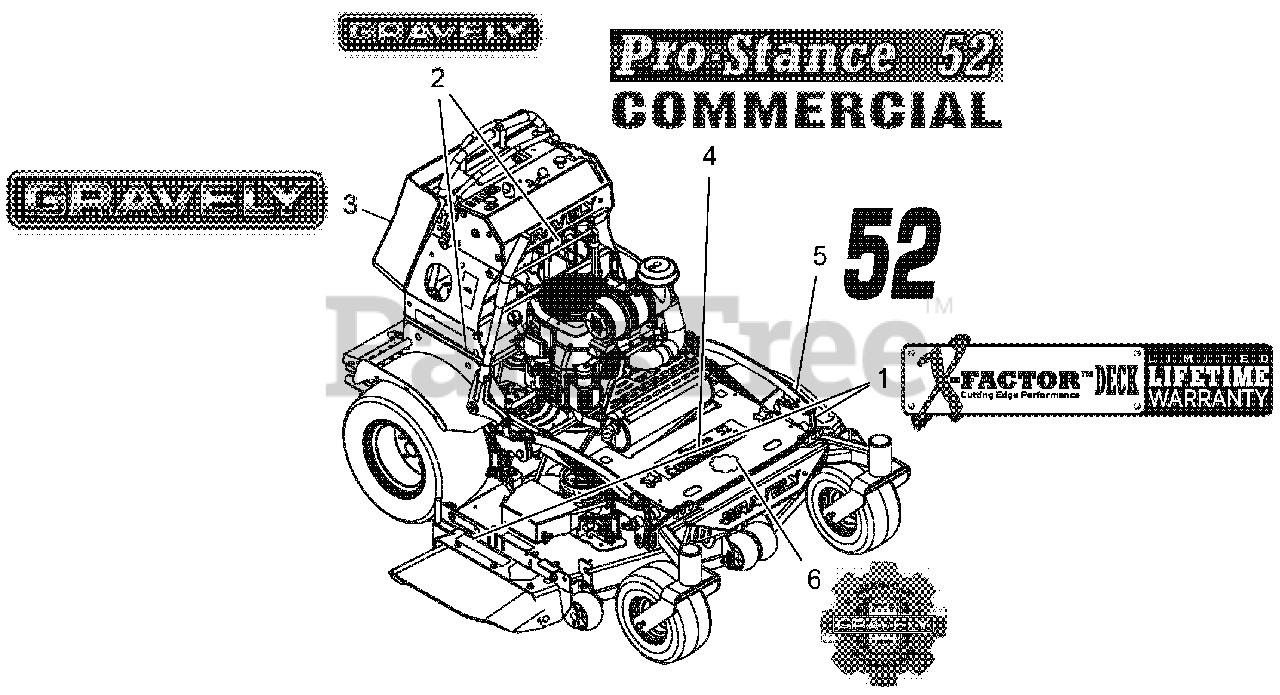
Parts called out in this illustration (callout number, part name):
1	DECAL, X-FACTOR DECK
2	DECAL, 9.5" GRAVELY LOGO
3	DECAL, FUEL TANK-GRAVELY
4	DECAL, PROSTANCE 52" 2011
5	DECAL, 52"
6	DECAL, GRAVELY HERITAGE-LARGE
